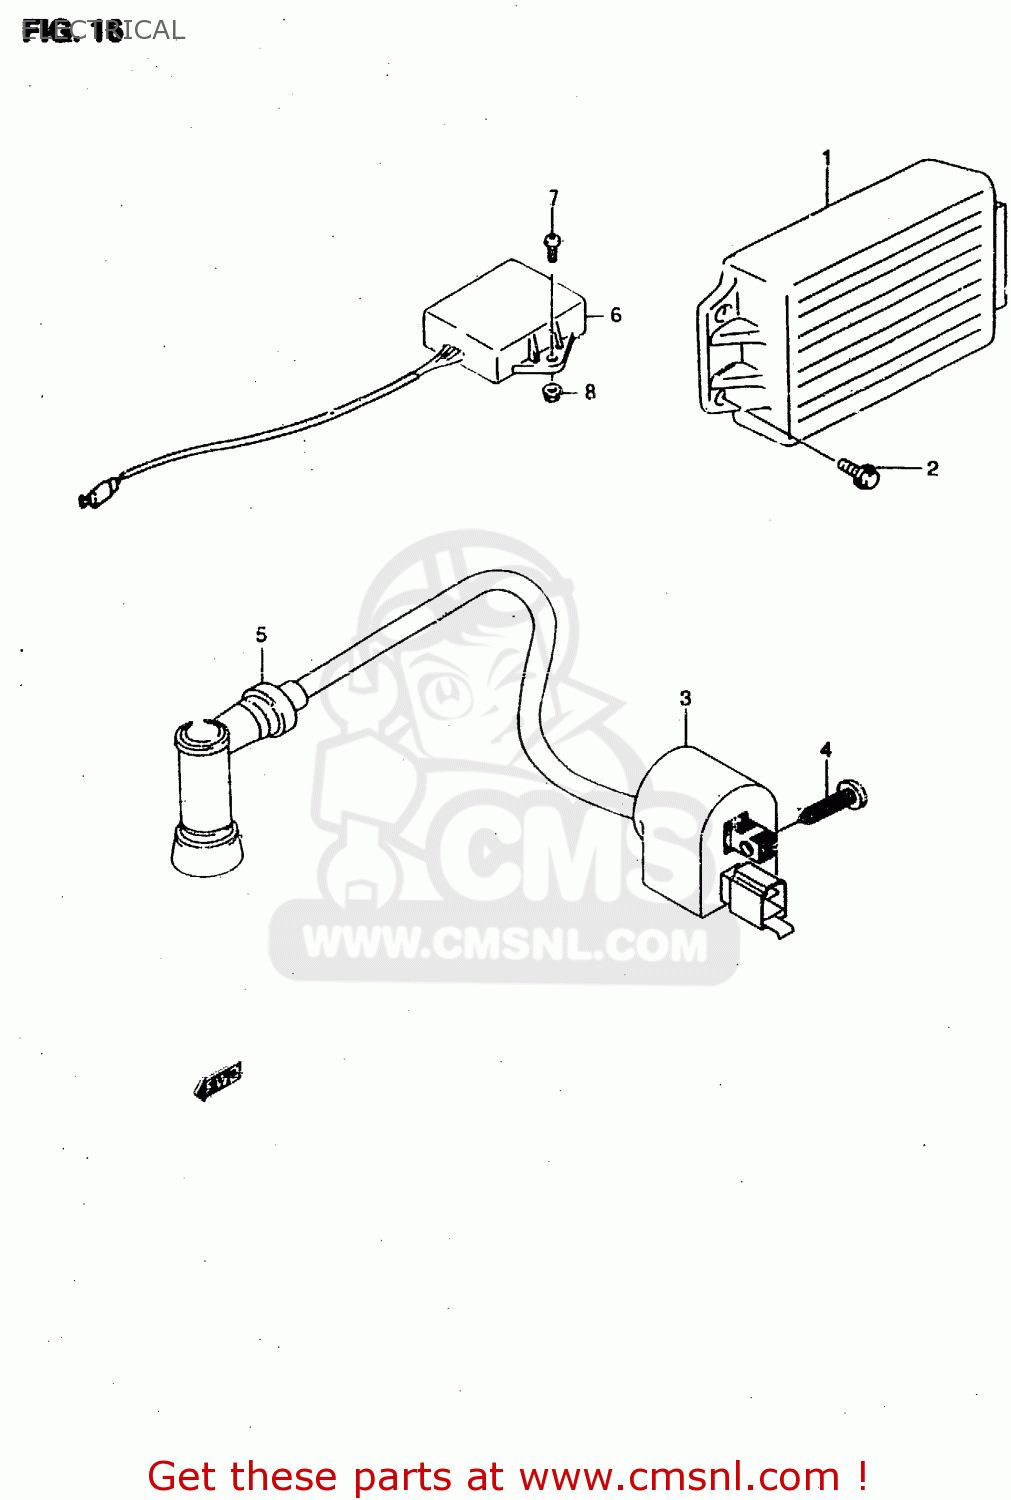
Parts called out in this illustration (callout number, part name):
1	RECTIFIER
2	BOLT
3	UNIT & COIL ASSY,IGNITION
4	SCREW 6X16
5	CAP ASSY, SPAR
6	UNIT ASSY,SIDE STAND INTERLOCK
7	SCREW 6X16
8	NUT
